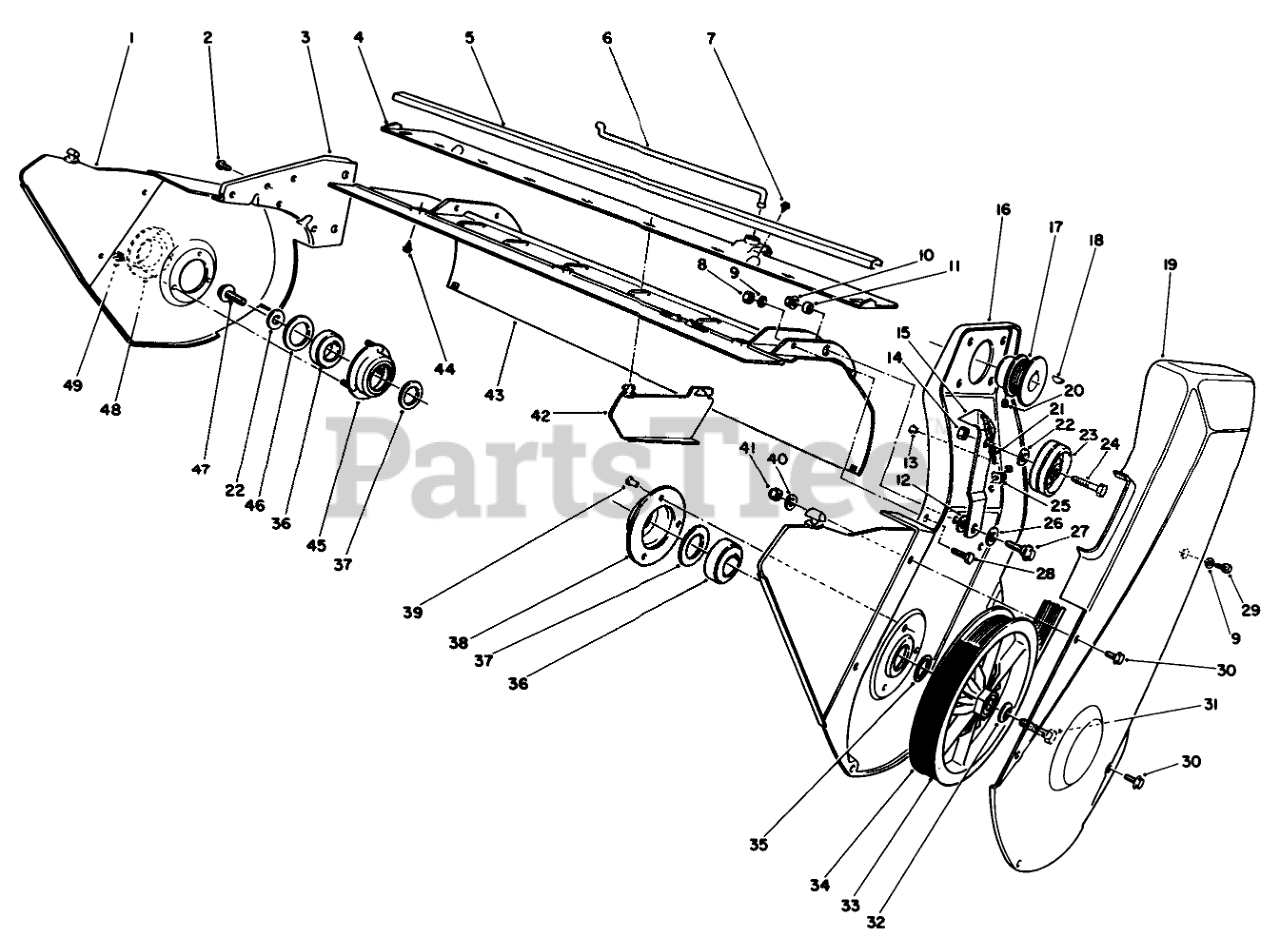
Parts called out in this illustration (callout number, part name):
1	OUTSIDE VANE
2	SCREW-HWH
3	Plate-R.H. Side
4	Mount-Vane
5	Moulding
6	VANE ADJ LINKAGE
7	10-16 X 3/8 THDG SCREW
8	NUT-LOCK, CONE
9	WASHER-FLAT
10	NUT-HF
11	SPACER
12	WASHER-PIVOT
13	Eyelet
14	NUT-LOCK, NI
15	IDLER ARM
16	Plate-L.H. Side
17	Pulley
18	KEY-WOODRUFF
19	Cover-Drive
20	SCREW-HSH
21	IDLER SPRING
22	WASHER-FLAT
23	IDLER PULLEY
24	SCREW-HH
25	TINNERMAN NUT
26	WASHER
27	SCREW-SHOULDER
28	SCREW-HH
29	SCREW-HEX HD
30	SCREW-SHWH
31	SCREW-HH
32	WASHER-BELLEVILLE
33	BELT - DRIVE
34	ROTOR PULLEY ASY
35	WASHER
36	BEARING-BALL
37	WASHER-THRUST
38	FLANGE-BEARING
39	RIVET
40	WASHER-FLAT
41	NUT-LOCK, NI
42	CENTER VANE
43	Housing
44	SCREW-HWHTF
45	FLANGE-BEARING
46	WASHER-RUBBER
47	SCREW-HHF
48	Trough
49	NUT-CAP
